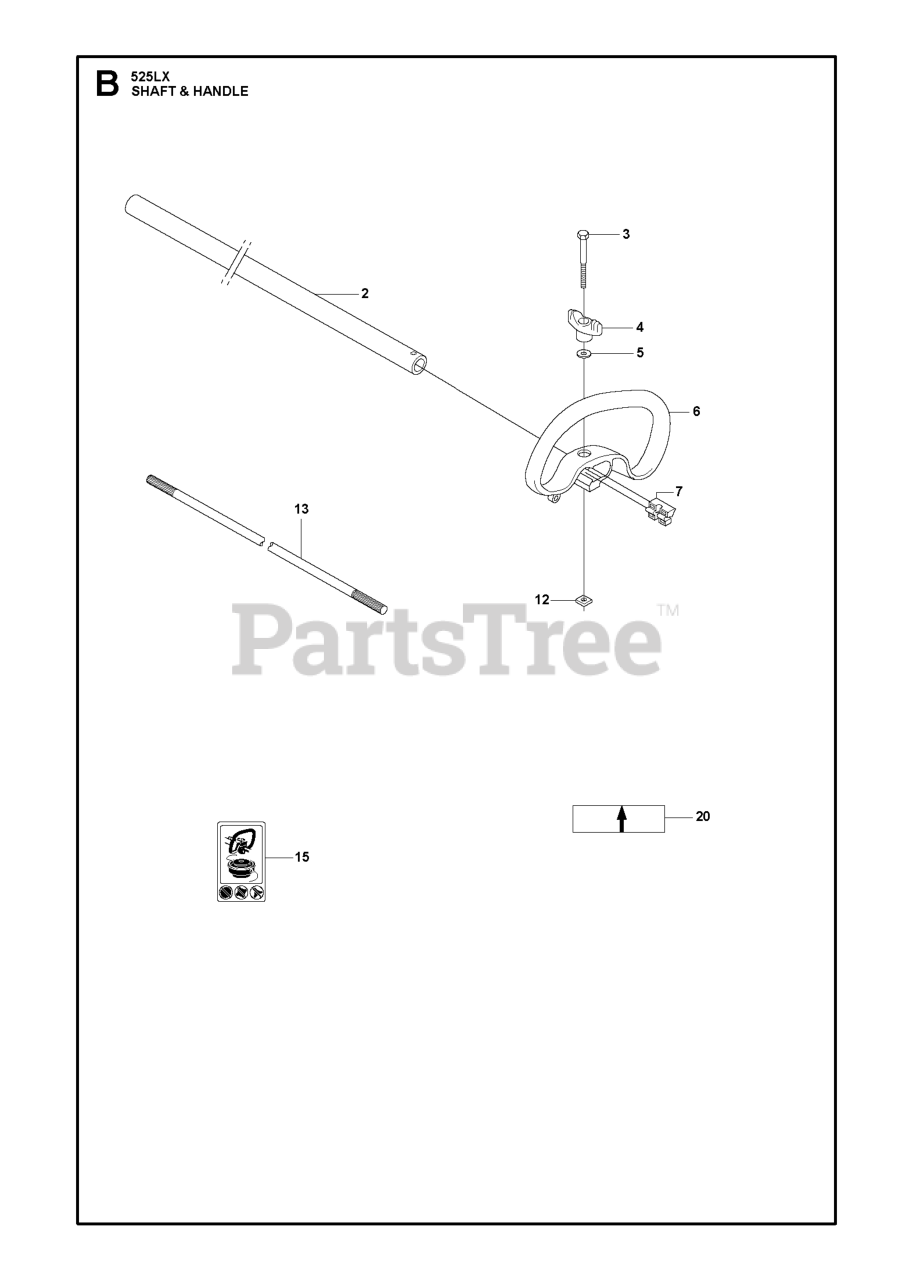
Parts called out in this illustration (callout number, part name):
2	TUBE COMP
3	SCREW M6X50
7	SPACER PLASTIC
13	DRIVESHAFT
15	DECAL WARNING "NO BLADES"
